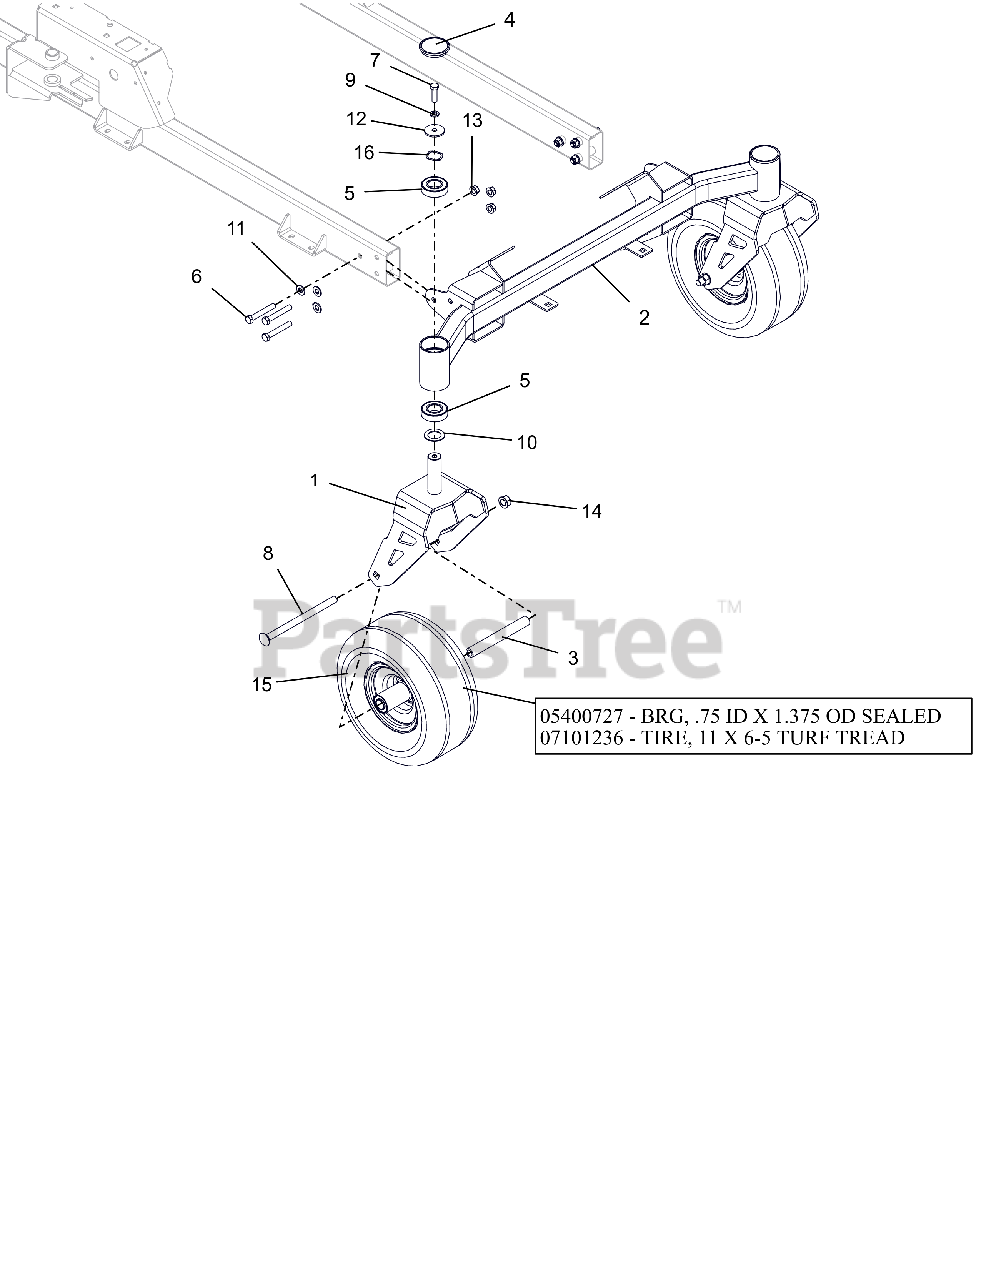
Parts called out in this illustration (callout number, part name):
1	WLDMT, CASTER FORK (WIDE)
2	WLDMT, AXLE FRONT
3	SPACER, FRONT WHEEL (WIDE 6.0)
4	CAP, DUST
5	BRG,BALL 1.00X2.00X.563(1641)
6	BLT-HEX .38-16X2.50 GR8 YWZC
7	@BLT-HEX .38-16X1.25 GR5 YWZC
8	@BLT-RDHDSQNK .50-13X7.50 G5YZ
9	@WSHR-LK .38X.094 REG YWZC
10	WSHR-HRD-THRS 1.007X1.542X.062
11	WSHR-HDND .406X.812X.055
12	WSHR-FL-STL .380X1.50X.125YWZC
13	NUT-LK-TOP-FLG .38-16 GRG YWZC
14	@NUT-LK-TOP-FLG .50-13 YWZC
15	TIRE/WHEEL ASSY, 11X6-5
15	BRG, .75 ID X 1.375 OD SEALED
15	TIRE, 11X6-5 TURF TREAD
16	WSHR-WAVE 1.0X1.25X.028 .145FH
